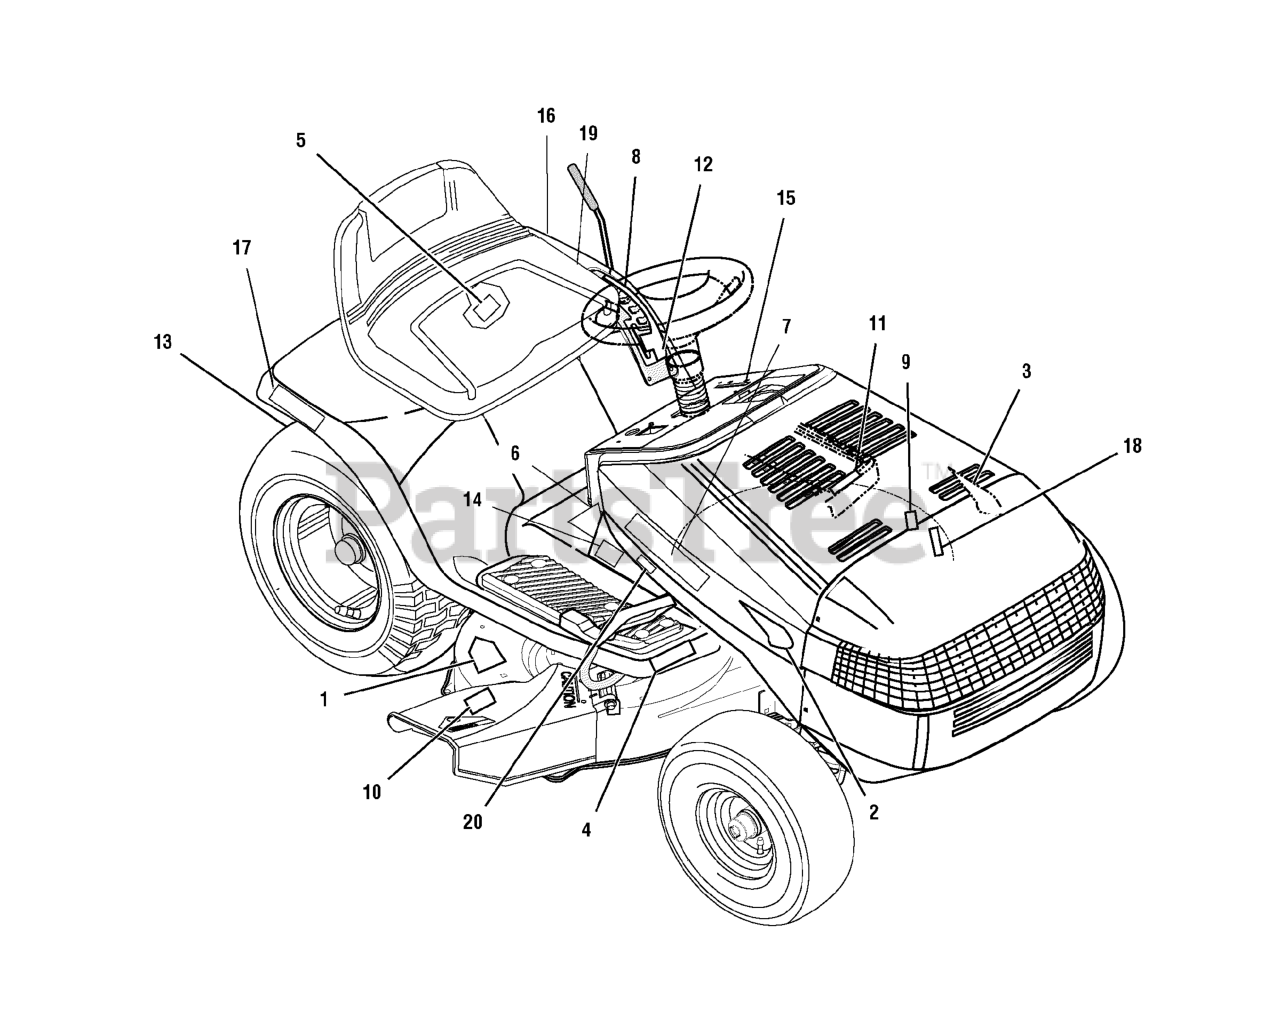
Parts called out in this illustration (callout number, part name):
1	DECAL, CUT FINGER ENGLISH
2	DECAL, MASPORT 15.5/40 RH
3	DECAL, MASPORT 15.5/40 LH
4	DECAL, V3-DC-5X2 HYDRO DRIVE
5	DECAL, HYDRO RELEASE DOM
6	DECAL, WARNING
7	DECAL, MASPORT LOGO
8	DECAL, 1/6 HGT ADJUST LIFT
9	DECAL, NO STEP LH HSNG
10	DECAL, NO STEP CHUTE
11	DECAL, CLUTCH/BRAKE SILVER
12	DECAL, DECK LEVEL POS/ONLY
13	DECAL, WARNING LOAD LMT
14	DECAL, BRIGGS LOGO
15	DECAL, DASH SYMBOLS 3510
16	DECAL, AUTOMATIC DRIVE
17	DECAL, AUTOMATIC DRIVE
18	DECAL, 3 WAY
19	DECAL, ENGAGE PTO
20	DECAL, V2-SS-1X3 CUTTING HEIGHT
